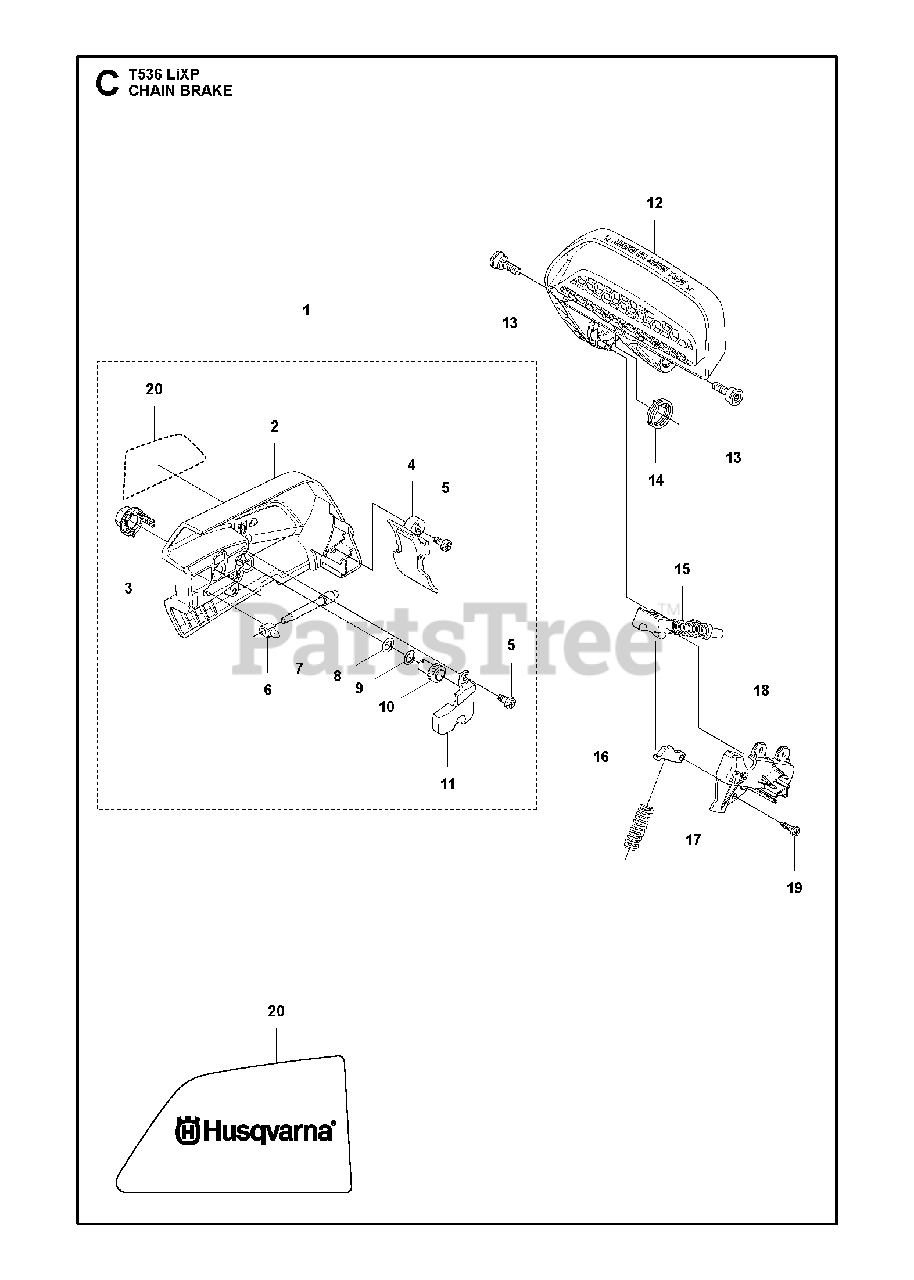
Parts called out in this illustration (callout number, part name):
1	CLUTCH COVER ASSY
2	CLUTCH COVER
3	NUT RETAINER ASSY
4	CHIP GUARD
5	SCREW
6	PAWL
7	SCREW
8	O-RING
9	WASHER
10	WORM WHEEL
11	COVER LID
12	HAND GUARD
14	TORSION SPRING
15	SHAFT ASSY
20	DECAL
